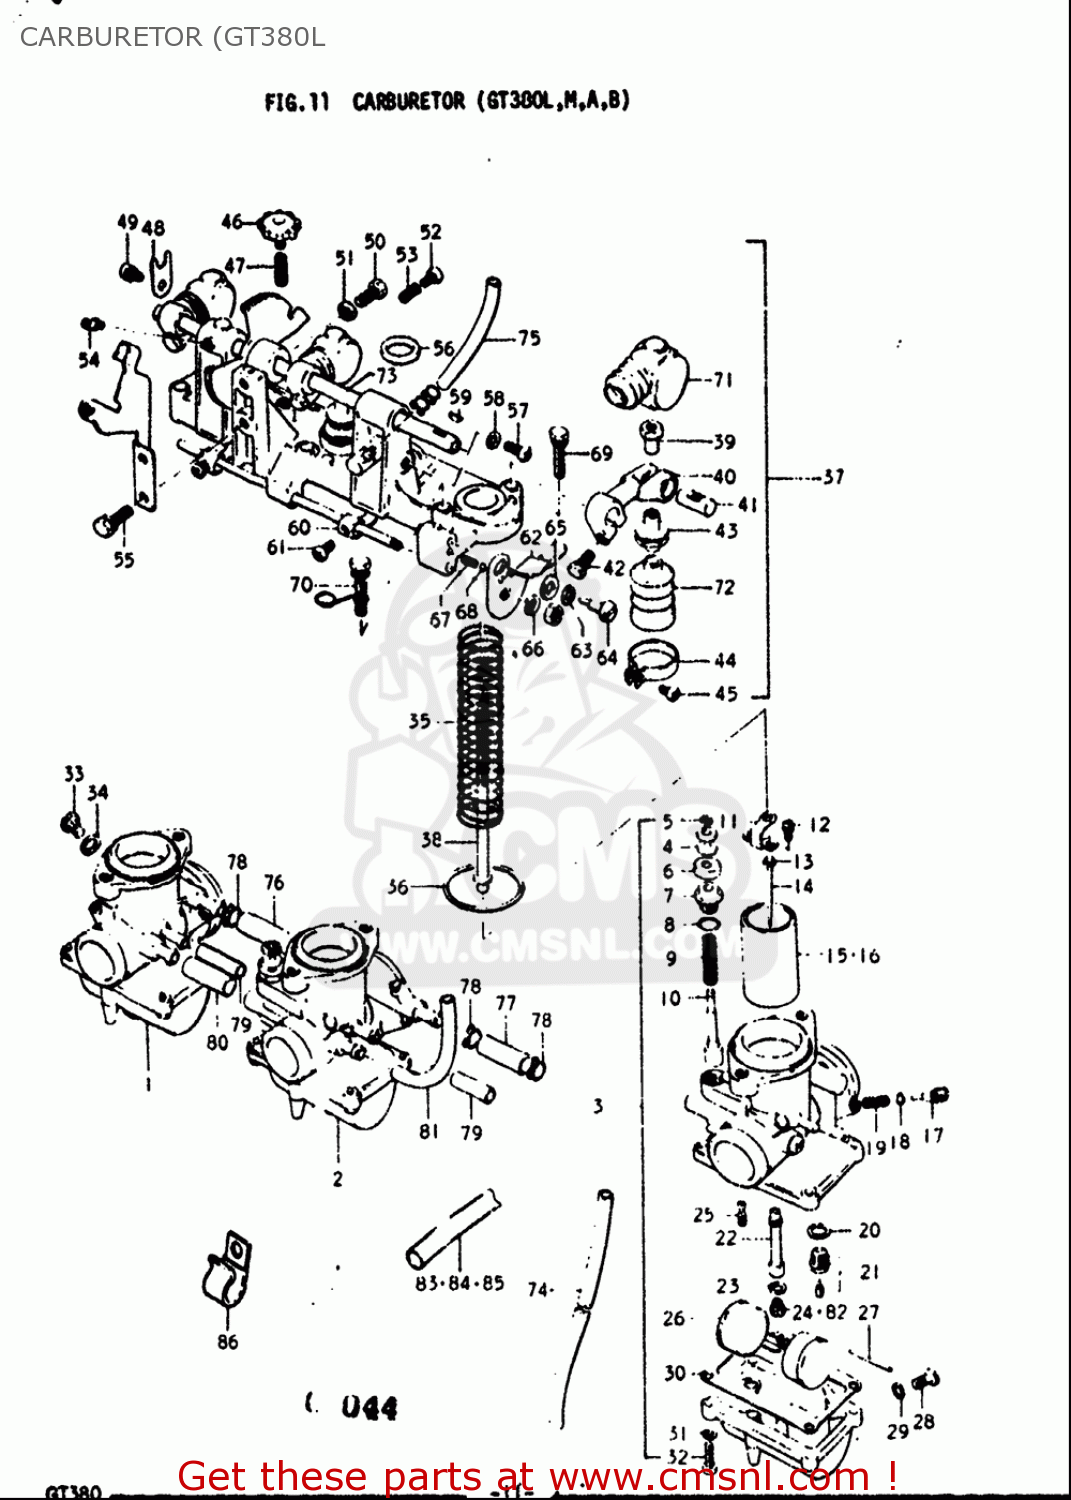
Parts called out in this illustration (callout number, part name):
4	RING
5	CLIP,CARBURETOR STARTER
6	CAP,PLUNGER
8	O RING(D:1.5,ID:8.5)
9	SPRING
12	SCREW
13	CLIP
14	NEEDLE,JET
17	SCREW,PILOT AIR ADJUSTING
18	O RING
19	SPRING
20	GASKET,VALVE SEAT (NAS)
21	VALVE ASSY,NEEDLE
23	WASHER
24	JET,MAIN
25	JET,PILOT(25)
26	FLOAT
27	PIN,FLOAT
28	PLUG
29	GASKET,DRAIN,PLUG (NAS)
30	GASKET,FLOAT CAHMBER (NAS)
31	WASHER,LOCK
32	SCREW 4X16
33	BOLT
34	GASKET,THRO VALVE INSPECTION (NAS)
36	O RING
40	ARM
45	SCREW
49	SCREW
50	SCREW(6X12)
53	SPRING,THROTTLE SCREW
54	NIPPLE
57	SCREW
61	SCREW
68	BALL,STARTER SHAFT
71	CAP,RUBBER
72	BOOT, THROTTLE VALVE
75	HOSE(4.5X8.5X600)
76	HOSE(6X10X600)
78	CLIP
79	HOSE,AIR BENT
81	HOSE(4.5X8.5X600)
82	JET,MAIN
83	HOSE(3X5X600)
84	HOSE(3X5X600)
85	HOSE(3X5X600)
86	CLAMP
